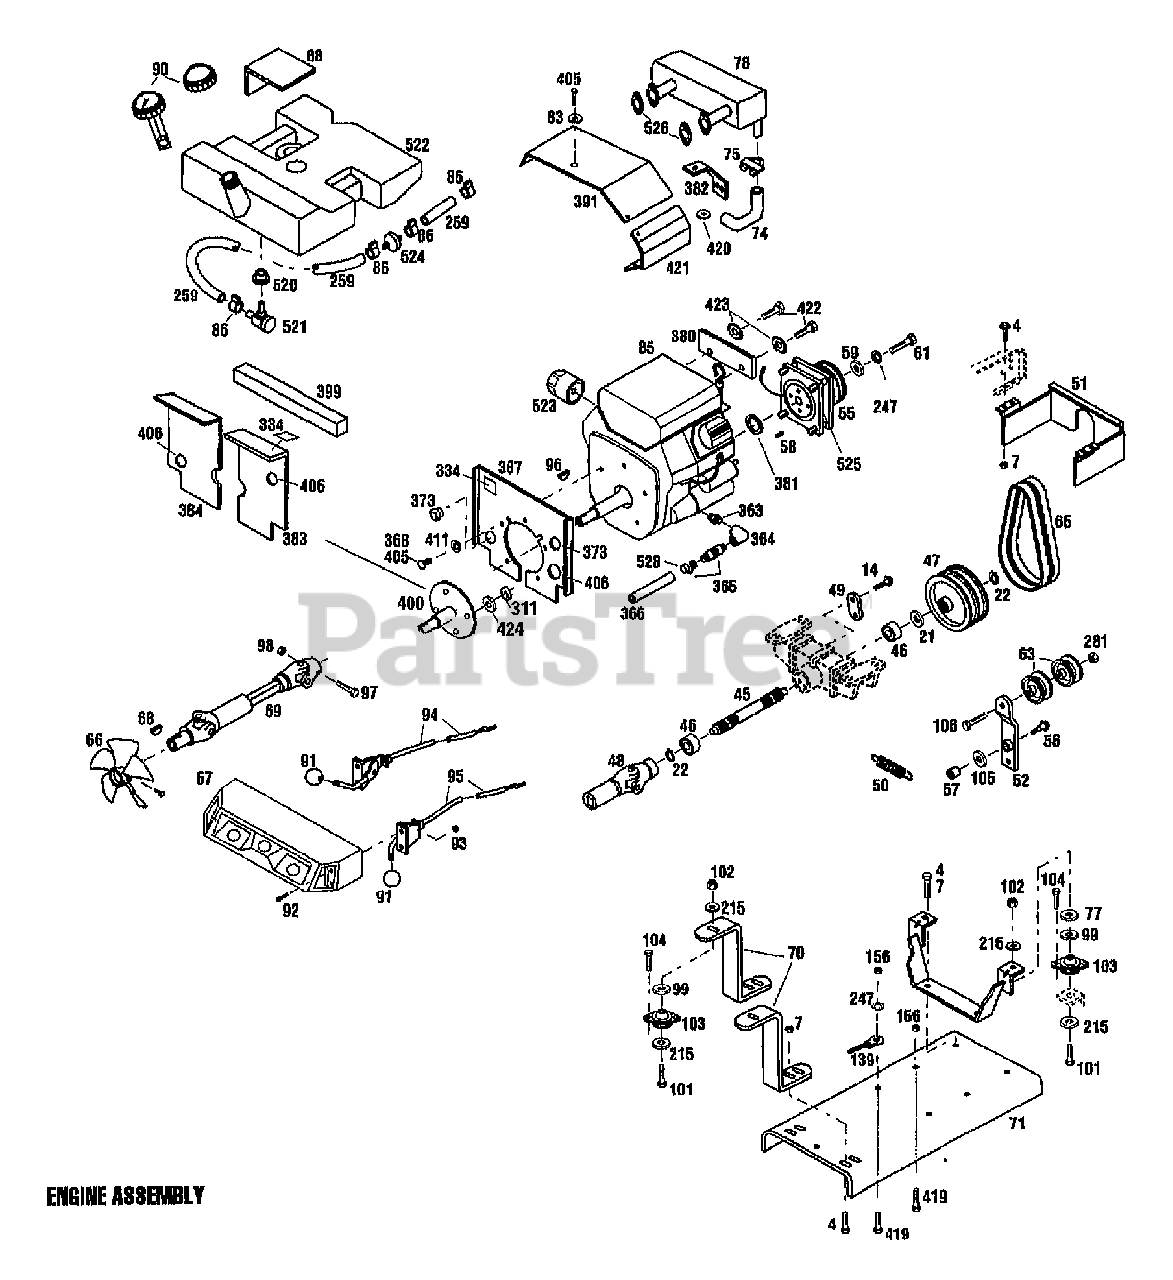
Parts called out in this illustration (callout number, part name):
7	NUT-HFLK 3/8-16 ZP
14	SCR-HFLK 5/16-18X.75 ZP
21	WASHER-THRUST
22	RING-HEAVY EXT HD 1.0 ID
45	SHAFT-PTO
46	BEARING-BALL
47	SHEAVE-PTO
48	JOINT-UNIVERSAL
49	ANCHOR-SPRING
51	GUARD-PTO
52	ARM-IDLER
55	BRAKE-CLUTCH GTX
57	BUSHING
57	BALL BEARING
59	WASHER-1.5X.375X.18 ZP
61	SCR-HH 3/8-24X1.5 G5
63	PULLEY-IDLER
65	BELT-V (SET OF 2)
67	BOLT-SQUARE HD SET
68	KEY-WOODRUFF .188X.75
69	SHAFT-DRIVE
70	SUPPORT-REAR BAR
71	PLATE-ENGINE MOUNTING
74	PIPE-EXHAUST
75	CLAMP-MUFFLER
77	WASHER-1.5X.375X.18 ZP
78	MUFFLER
83	WASHER-LK .25 ZP
85	ENGINE, BRIGGS & STRATTON 16HP, 303447
86	CLAMP-HOSE
88	PAD-FUEL TANK
90	GAUGE-FUEL
91	KNOB
93	NUT W/LKWASHER 10-24 ZP
94	CHOKE-CONTROL
95	CONTROL-THROTTLE
96	KEY-WOODRUFF .25X.875
97	SCR-HH 1/4-20X2.0 G5 ZP
98	NUT-HT LK 1/4-20
99	WASHER
101	SCR-HH 3/8-16X2.25 G5 ZP
102	NUT-LOCK 3/8-16
103	MOUNT-FRONT
105	WASHER-1.115X.637X.06
106	SCR-HH 3/8-16X2.25 G5 ZP
139	CABLE (-)
215	WASHER-FLAT 1.25X.406X.179
247	WASHER-LK .375 @ DEPL
259	LINE-FUEL 52"
281	SCR-HXSKT 5/16-18X.75 BO
311	NUT-PUSH
334	DECAL-WARNING
364	ELBOW-90 DEGREES
365	ASSM-OIL VALVE
366	HOSE-DRAIN
367	SHIELD-HEAT
373	GROMMET-SNAP BUSHING
380	CLUTCH-STOP
381	SPACER-CRANKSHAFT
382	SUPT-EXHAUST PIPE
383	SHIELD-GRASS RT W/DECAL
384	SHIELD-GRASS LEFT
391	SHIELD-HEAT
399	SEALING STRIP
400	ASSM-EXTENSION (CRANKSHAFT)
405	SCR-HH M6X8
406	BUSHING
411	WASHER-LK INTERNAL TOOTH 1/4
419	SCR-HFLK 5/16-18X1.75 ZP G5
420	WASHER-STAR
421	SHIELD-HEAT
422	SCR-HH 3/8-16X1.5 G5 ZP
423	(BUY LOCAL)
424	WASHER-.505X.22X.05
520	BUSHING-RUBBER
521	VALVE-SHUT OFF
522	ASSM-FUEL TANK
523	OIL FILTER
524	FILTER-FUEL
526	MUFFLER GASKET
528	CAP-OIL DRAIN
